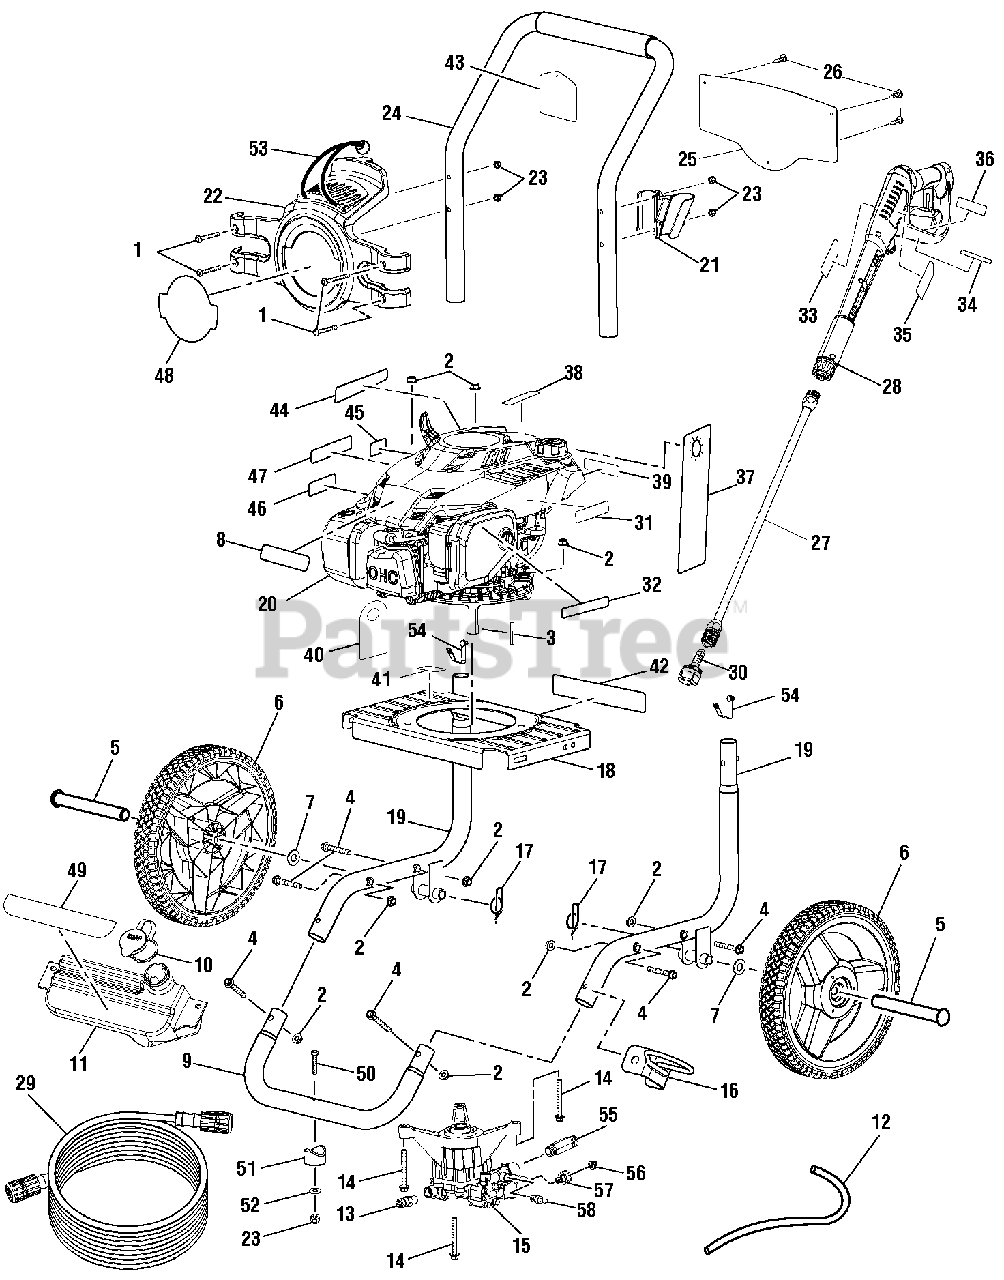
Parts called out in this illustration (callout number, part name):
1	Screw (1/4-20 x 2 in., T30 Torx Hd.)
2	Flange Nut (M8 x 1.25 in.)
3	Output Shaft Key (35mm)
4	Bolt (M8 x 55 mm)
7	Washer (1/2 in.)
8	Subaru Label
9	Front Frame Assembly
10	Soap Tank Cap
11	Soap Tank
12	Chemical Siphon Tube
13	Thermal Release Valve
14	Bolt (M8 x 60 mm, Flange Hd.)
16	Wand Holder Loop
17	Ring Clip
18	Engine Plate
19	Main Frame Assembly
21	Wand Holder
22	Hose Assembly
23	Lock Nut (1/4-20 in.)
24	Handle w/Foam
25	Quick Start Panel
26	Screw (#6-20 x 3/8 in., T10 Torx Pan Hd.)
27	Spray Wand Assembly
28	Trigger Handle Assembly
29	Hose (25 ft.)
30	5-in-1 Change Over Nozzle
31	Engine Start Label
32	Inquiries Label
33	Label (Trigger Handle Logo)
34	Label (Trigger Handle Specifications)
35	Label (Trigger Handle Warning)
36	Label (Trigger Handle Warning, French & Spanish)
37	Warning Hangtag
38	E85 Label
39	Do Not Mix Label
40	Oil Cap Hangtag
41	Oil Fill Location Label
42	Data Label
43	Nozzle Hangtag
44	Release Water Label
45	Lubricant Label
46	Hot Surface Label
47	Combustion Label
48	Performance Label
49	Detergent Tank Label
50	Screw (1/4-20 x 1.85 in., T30 Torx Hd.)
52	Washer (1/4 in.)
53	Bungee Cord Assembly
54	Spring Clip
55	Filter Screen
56	Outlet Tube
57	Inlet Tube
58	Detergent Suction Kit
